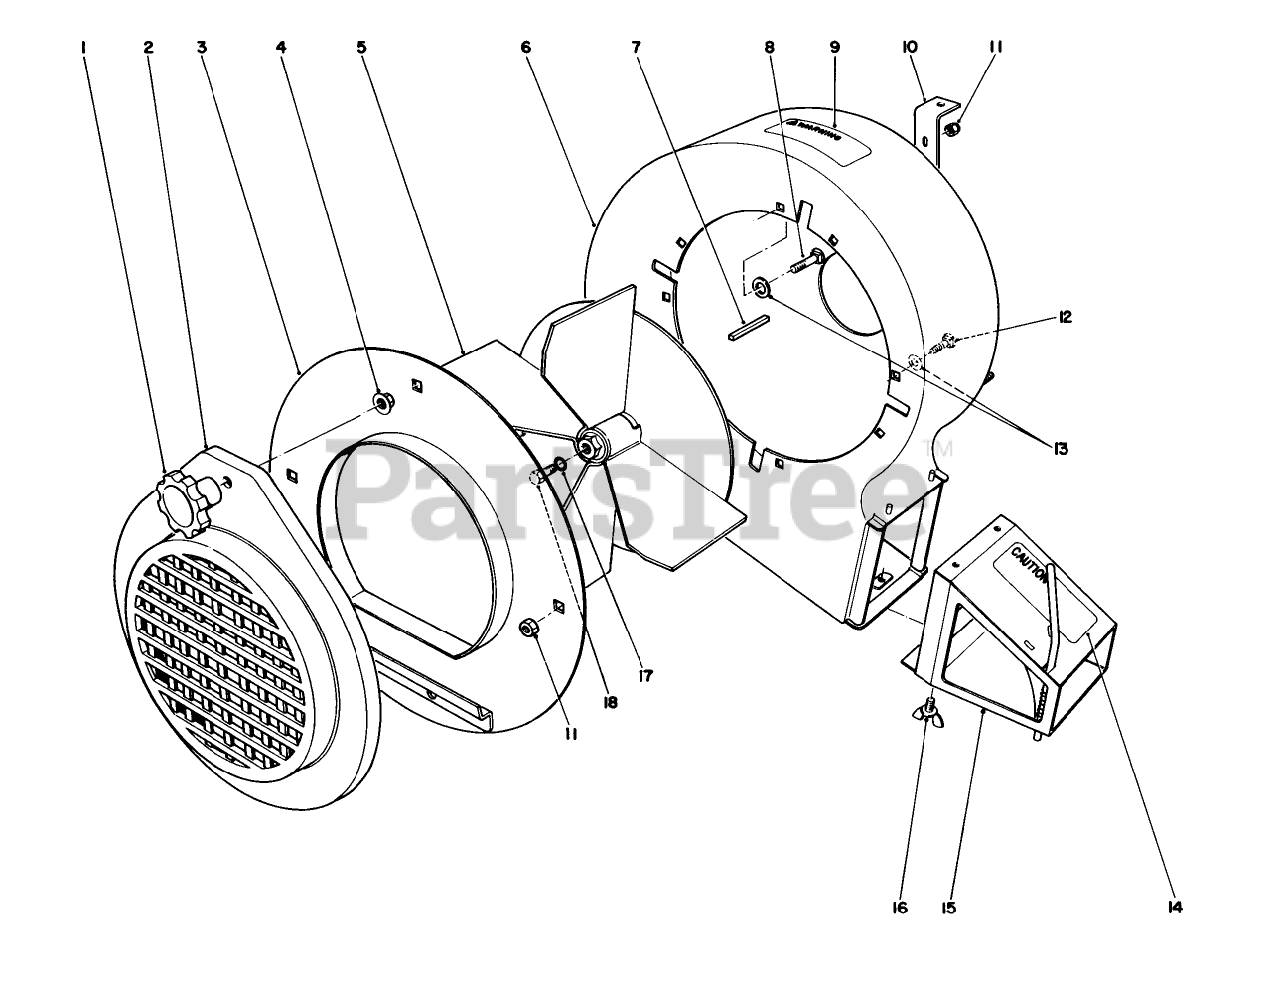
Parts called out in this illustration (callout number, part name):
2	INTAKE-BLOWER
4	NUT-FLANGE
7	KEY-SQUARE
8	BOLT-CARRAIGE
11	NUT-LOCK, CONE
12	BOLT-CARR
13	WASHER-FLAT
16	1/4 - 20 3/4 WING SCR
17	WASHER-LOCK
